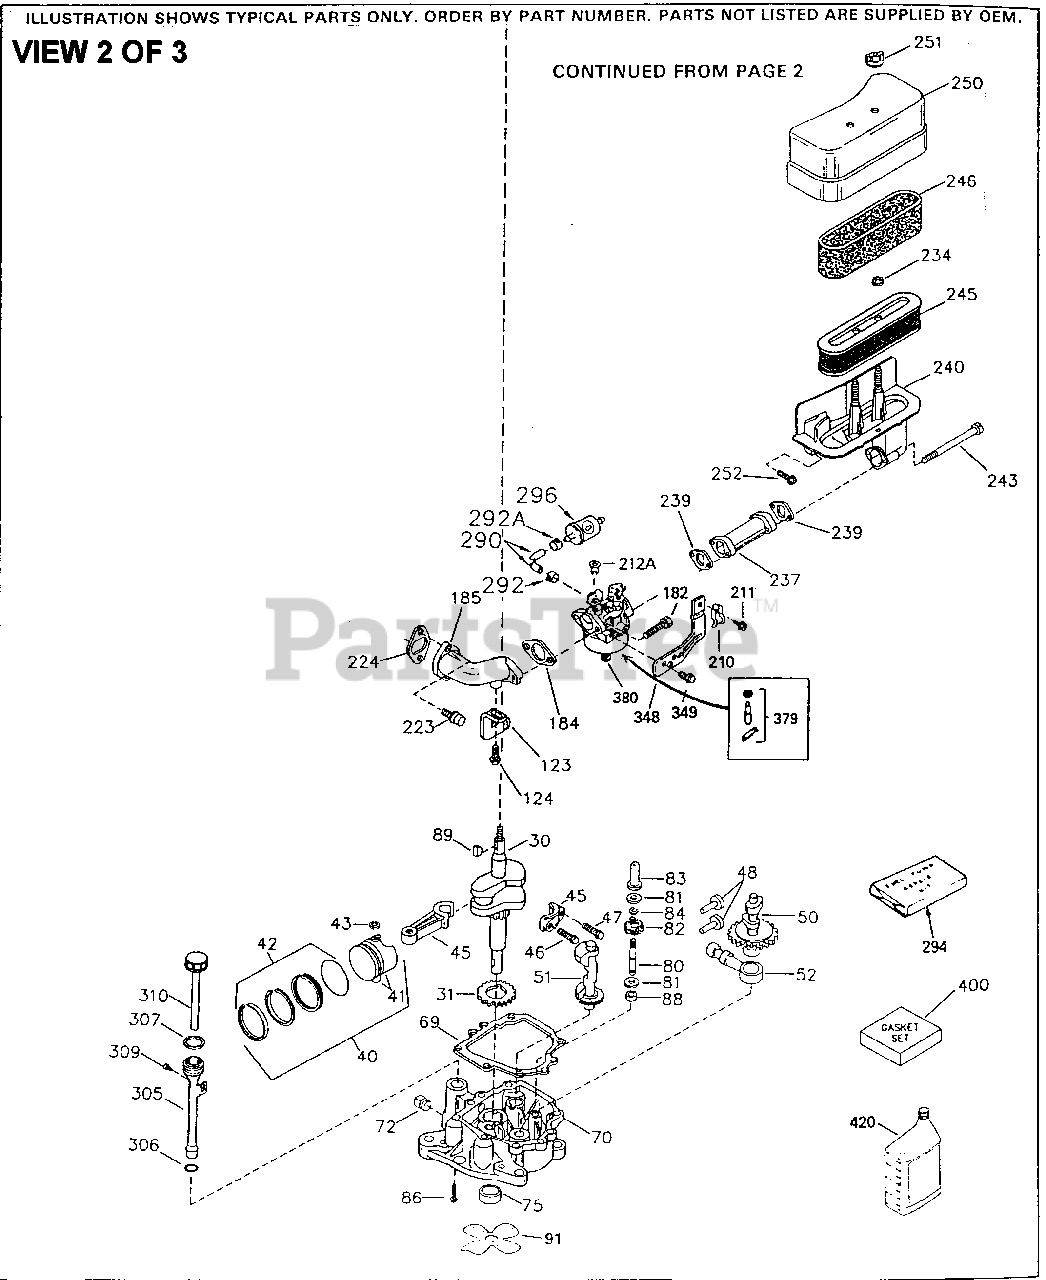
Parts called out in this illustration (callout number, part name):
28	Lock Nut, 8-32
30	Crankshaft
31	Counterbalance Gear
40	Piston, Pin & Ring Set (Std.)
40	Piston, Pin & Ring Set (.010" OS)
40	Piston, Pin & Ring Set (.020" OS)
41	Piston & Pin Ass'y. (Std.) (Incl. 43)
41	Piston & Pin Ass'y. (.010" OS) Incl. 43
41	Piston & Pin Ass'y. (.020" OS) Incl. 43
42	Ring Set (Std.) (3-5/16")
42	Ring Set (.010" OS)
42	Ring Set (.020" OS)
43	Piston Pin Retaining Ring
45	Connecting Rod Ass'y. (Incl. 46 & 47)
46	Connecting Rod Bolt
47	Connecting Rod Bolt
48	Valve Lifter
50	Camshaft (MCR)
51	Counterbalance Weight
52	Oil Pump Ass'y.
69	* Mounting Flange Gasket
70	Mounting Flange (Incl. 72, 75 & 80)
72	Oil Drain Plug
75	Oil Seal
80	Governor Shaft
81	WASHER
82	Governor Gear Assembly
83	Governor Spool
84	Retaining Ring
86	Screw, 1/4-20 x 1-3/16"
89	Flywheel Key
123	Intake Pipe Brace
124	Screw, 1/4-20 x 5/8"
182	Screw, 1/4-20 x 27/32"
184	* Carburetor To Intake Pipe Gasket
185	Intake Pipe
210	Conduit Clip
211	Screw, 10-32 x 3/8"
212A	Bushing
223	Screw, Torx T-30, 5/16-18 x 7/8"
224	* Intake Pipe Gasket
234	Nut & Lock Washer, 1/4-20
237	Air Filter Adapter
238	Screw, 10-32 x 5-1/4"
239	* Air Cleaner Gasket
240	Air Cleaner Body (Incl. 239)
245	Air Filter (Incl. 234) also available in Packaged Part #740015B
245A	Pre-Cleaner Air Filter also available in Packaged Part #740015B
250	Air Cleaner Cover
251	Wing Nut, 1/4-20
261	Screw, T-30, 1/4-20 x 1/2"
262A	Screw, 5/16-24 x 25/32"
264A	Screw, T-30, 1/4-20 x 1/2"
290	Fuel Line
292	Fuel Line Clamp
296	Fuel Filter (Incl. 292) also availabl e as Packaged Part #740003B
305	Oil Fill Tube
306	"O" Ring
307	"O" Ring
310	Dipstick
337	Deflector
380	Carburetor (Incl. 184)
400	* Gasket Set (Incl. items marked PK in notes) Incl. part #'s 27896 (2), 3326 3 (1), 33629 (2), 34265 (1), 35317 (1 ), 35762 (2), 35946 (1), 35952 (1), 3 5958 (1)
